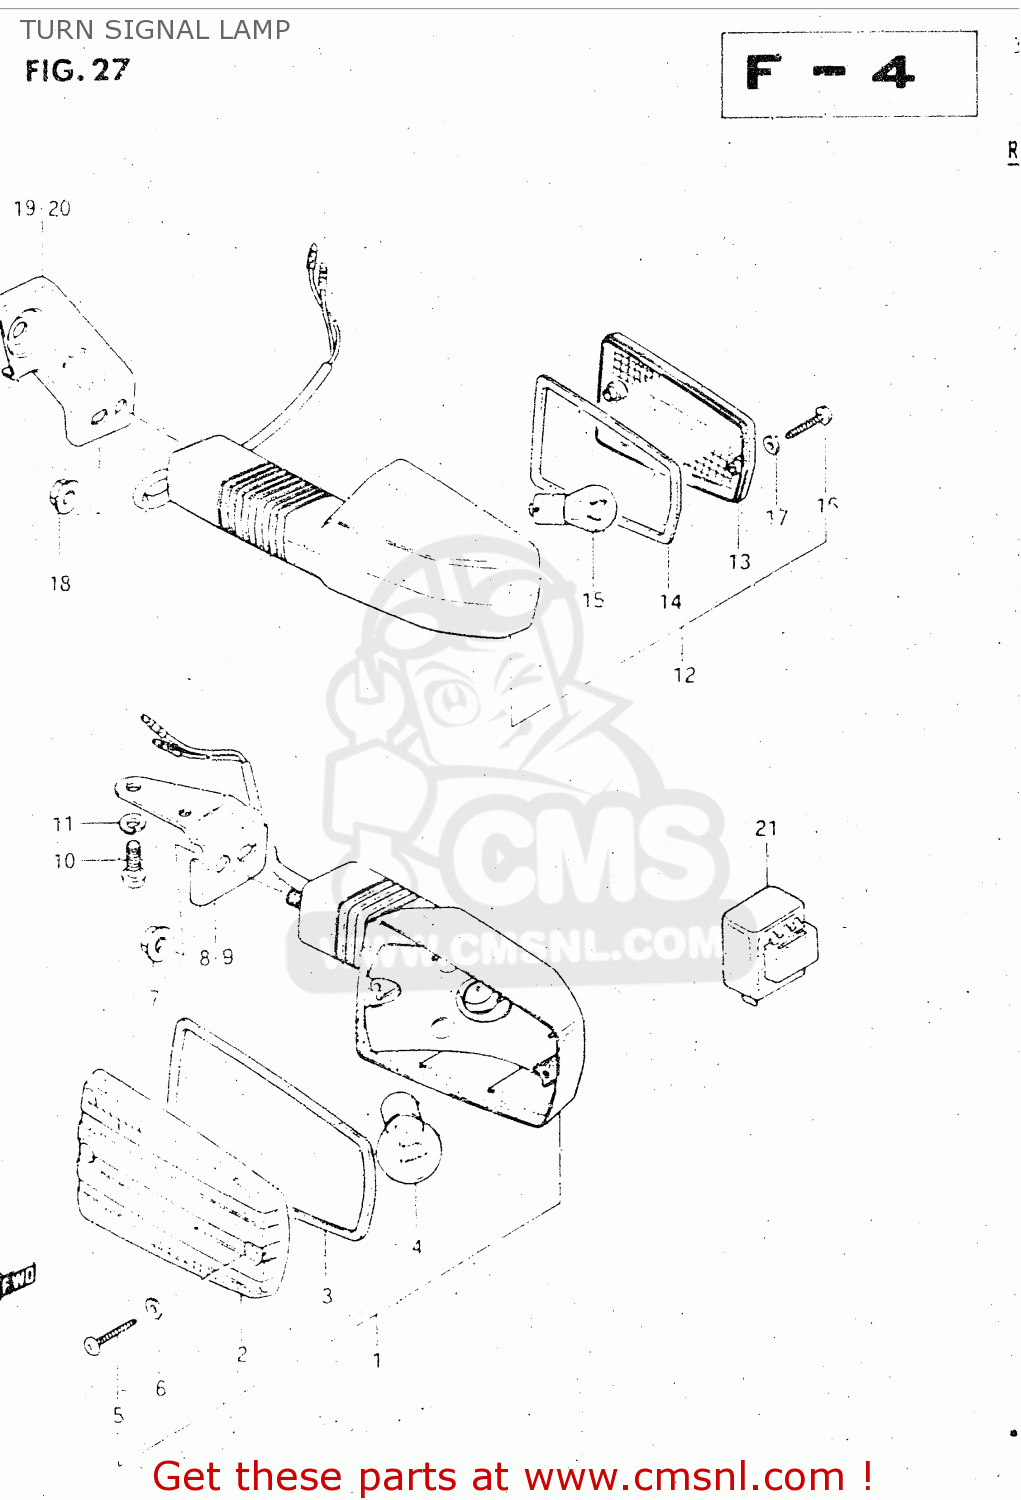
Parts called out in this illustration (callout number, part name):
1	LAMP ASSY, FRONT TURN SIGNAL
2	LENS
3	GASKET (NAS)
4	BULB(12V21W)
5	SCREW
6	GASKET (NAS)
7	NUT M8
8	BRACKET,FRONT TURN SIGNAL
9	BRACKET,FRONT TURN SIGNAL
10	SCREW
11	WASHER,LOCK
12	LAMP ASSY, REAR TURN SIGNAL
13	LENS,TURN SIGN
14	GASKET (NAS)
15	BULB(12V21W)
16	SCREW
17	GASKET (NAS)
18	NUT
19	BRACKET,REAR TURN SIGNAL
20	BRACKET,REAR TURN SIGNAL
21	RELAY ASSEMBLY,TURN SIGNAL
